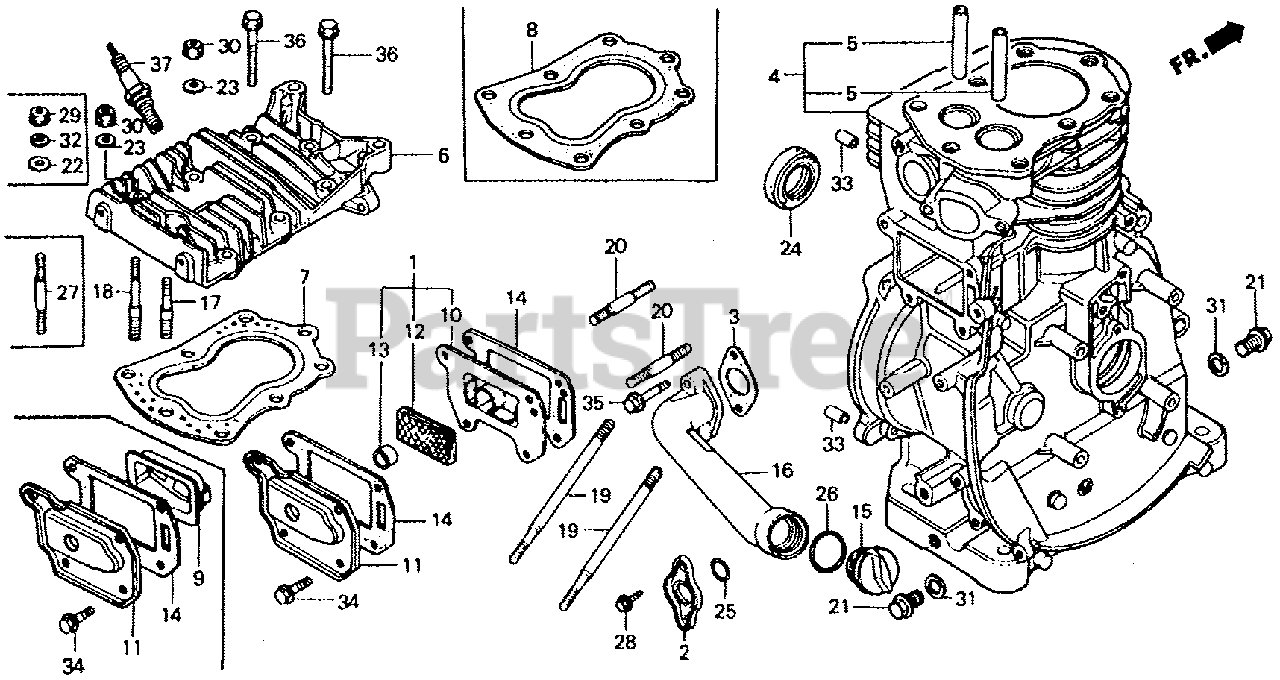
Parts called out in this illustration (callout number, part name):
1	CASE KIT, BREATHER
2	COVER, OIL PAN
3	GASKET, OIL PAN
4	CYLINDER (CRANKSHAFT P.T.O.)
4	CYLINDER
5	GUIDE, VALVE
6	CYLINDER HEAD
7	GASKET, CYLINDER HEAD
9	CASE, BREATHER
10	CASE, BREATHER
11	COVER, TAPPET
12	FILTER, BREATHER
13	SEAL, BREATHER
14	GASKET, TAPPET COVER
15	CAP, OIL
16	PIPE, OIL
17	BOLT, STUD (M8XM10X63)
18	BOLT, STUD (M8XM10X81)
19	BOLT, STUD (8X110)
19	BOLT, STUD (8X104)
20	BOLT, STUD (8X35)
21	BOLT, DRAIN PLUG
22	WASHER, HEAD (8MM)
23	WASHER (8MM)
24	OIL SEAL (25X41X6)
25	O-RING (27X2.0)
26	O-RING (26X2.7)
27	BOLT, STUD (8X80) (NOT AVAILABLE)
27	BOLT, STUD (8X45)
28	BOLT-WASHER (6X12)
29	NUT, FLANGE (8MM)
30	NUT-WASHER (8MM)
31	WASHER, DRAIN PLUG (12MM)
32	WASHER, SPRING (8MM)
33	PIN A, DOWEL (8X14)
34	BOLT, FLANGE (6X12)
35	BOLT, FLANGE (6X25)
36	BOLT, FLANGE (8X50) (NOT AVAILABLE)
37	SPARK PLUG (B-4H)
37	SPARK PLUG (BR-4HS) (NGK)
37	SPARK PLUG (W14F-U) (DENSO)
37	SPARK PLUG (W14FR-U) (DENSO)
37	SPARK PLUG (BPR4HS-10) (NGK)
37	SPARK PLUG (BP4HS-10) (NGK)
37	SPARK PLUG (W14FP-UL10) (DENSO)
37	SPARK PLUG (W14FPR-UL10) (DENSO)
37	SPARK PLUG (W20FS-U) (DENSO)
37	SPARK PLUG (W20FP-U10) (DENSO)
